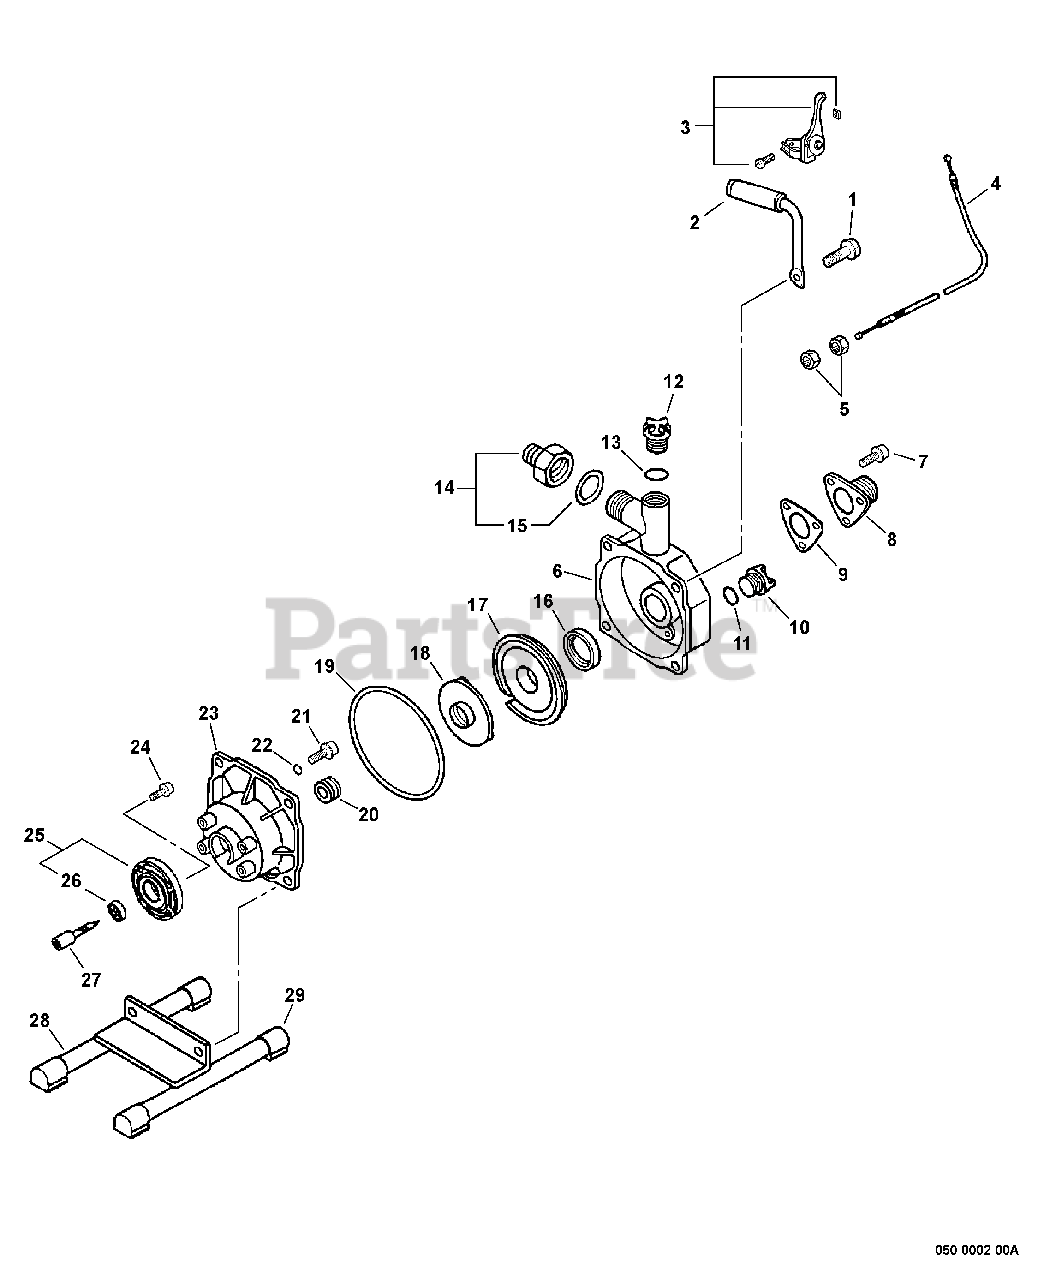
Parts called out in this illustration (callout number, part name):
1	BOLT - 8X35 -- TAPPING
3	THROTTLE CONTROL KIT
4	CABLE, THROTTLE
6	CASE, PUMP
7	BOLT - 6X20
8	CASE, CHECK VALVE
9	VALVE, CHECK
11	O-RING - 24
14	NIPPLE - 1 X 3/4"
17	CASE, IMPELLER
18	IMPELLER
21	SCREW - 5X25
23	CASE, PUMP
24	PUMP ADAPTOR ASSY
25	BEARING, BALL - 6201
26	SCREW - 5X25
27	SHAFT, PUMP
28	FRAME, PUMP
